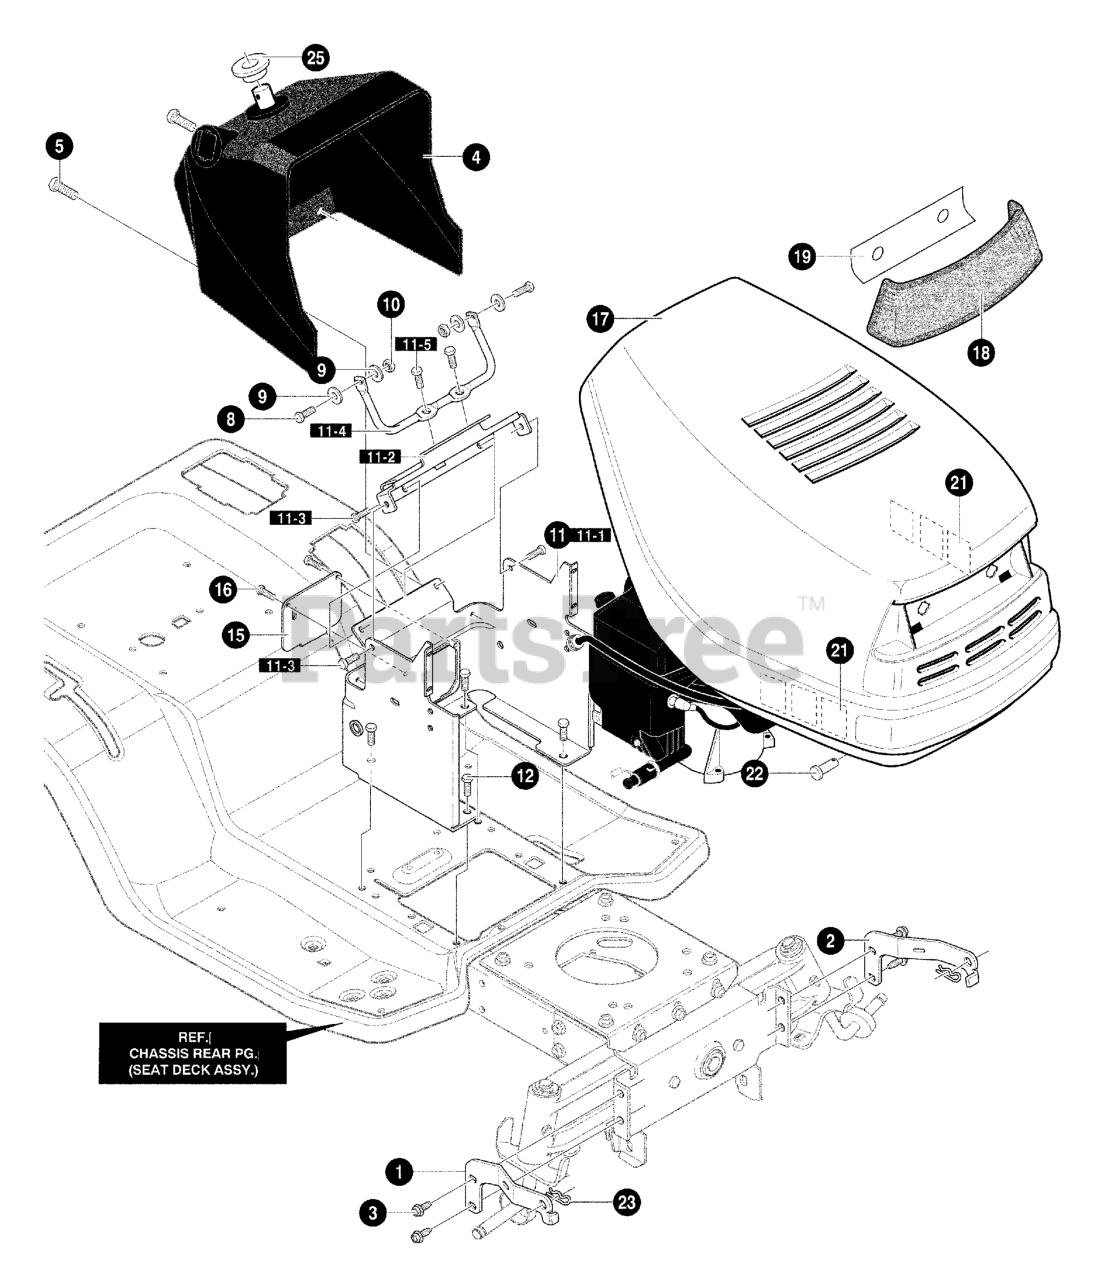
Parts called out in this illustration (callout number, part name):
1	BRACKET, HOOD RH- H15
2	BRACKET, HOOD LH- H15
3	SCREW, 5/16-18 x 0.75
4	DASH, H14/H15
5	SCREW, 1/4- 14X .75PHPANTAPABBL
8	SCREW, 1/4-20X .75 HHC
9	WASHER, FLAT .281X .63X.065
10	NUT, 1/4-20 REGHEXCTRLK
11	ASM. LOWER CONSOLE H14/H15
11-1	TOWER, LOWER DASH
11-2	SUPPORT, STEERING/PTO
11-3	SCREW, 1 /4- 20X .50 WAHHTAP
11-4	ROD, DASH BRACE
11-5	SCREW, 1/4-20X .50 WAHHTAP
12	SCREW, 5/16-18 x 0.75 HHWATAPSGIBP
15	PANEL, ACCESS NLT
16	SCREW, 10-24X.500 TRSEGI ZNBKCR
17	HOOD, NOMA LARGE H- 15
18	LENS, HEADLAMP DYNA HOODS
19	FOIL, LENS DYNA HOOD REFLECTOR
21	FOIL, HEAT REFLECTOR
22	PIN, CLEVIS .375DIA.X .81 LG
23	PIN, HAIR.38 DIAX1.64LGPH&OI/Z
25	BUSHING, STEERING SHAFT
